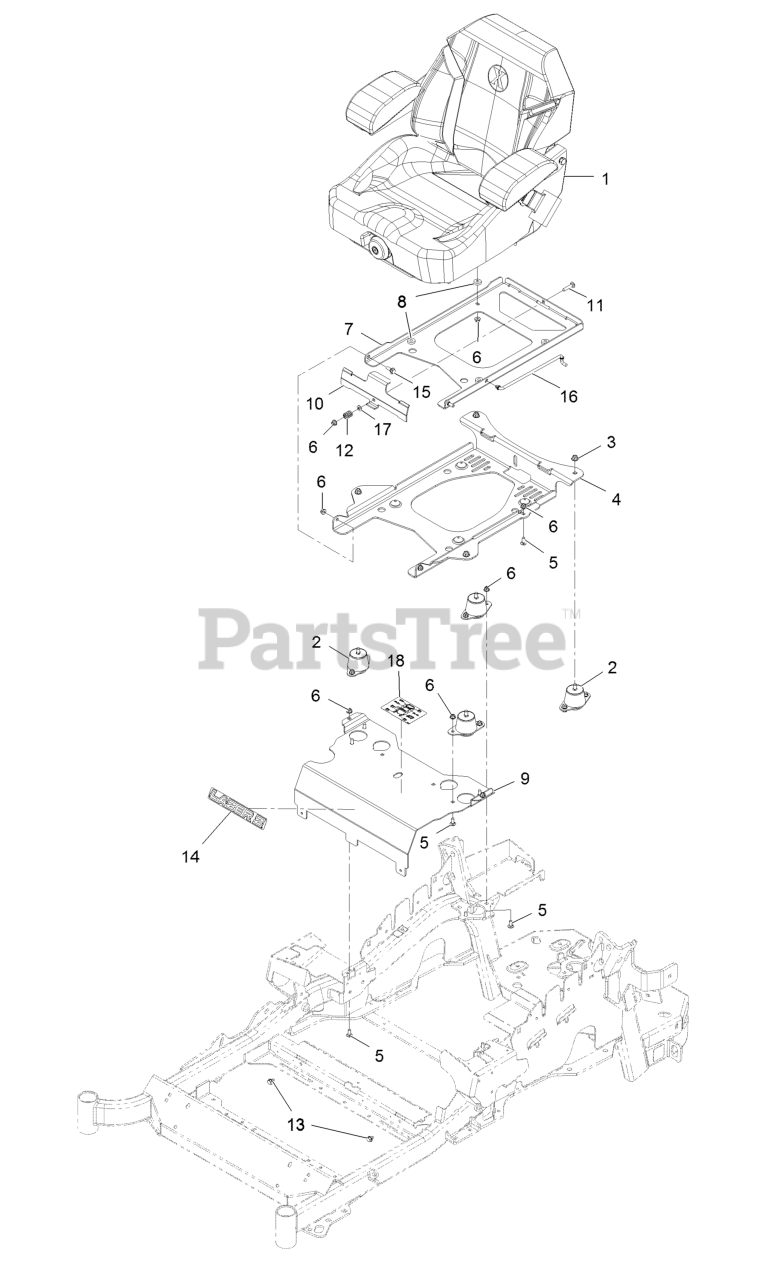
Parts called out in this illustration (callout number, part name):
1	KIT-SUSPENSION SEAT
2	ISOLATOR-SEAT
3	NUT-HF, NI
4	PLATE-TILT, SEAT SUPPORT
5	SCREW-CARR
6	NUT-HF, NI
7	PLATE-FRAME, SEAT
9	Panel-Front, Seat Mount
10	PLATE-LATCH, SEAT
11	BOLT-CARR
12	SPRING-COMPRESSION
14	DECAL, LAZER MODEL
15	SCREW-SHOULDER
16	ROD-PROP
17	WASHER-PLAIN
18	DECAL-SERVICE AID
